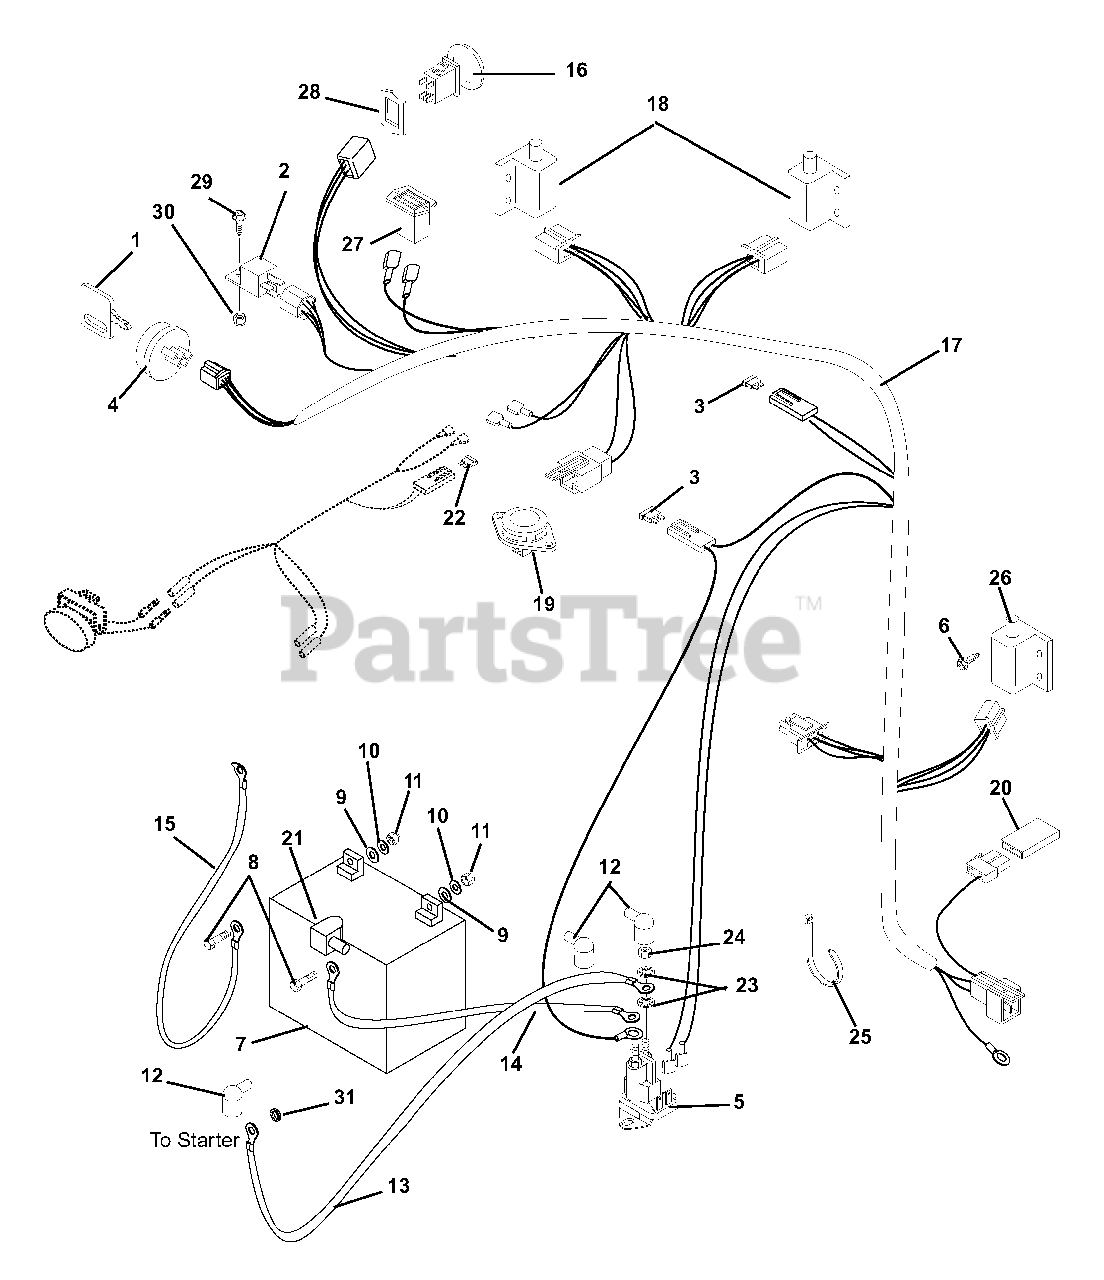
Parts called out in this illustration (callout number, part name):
1	KEY -W/CAP
2	RELAY
3	FUSE-25 AMP ATC TYPE
4	KEY SWITCH
5	SOLENOID
6	@SCR-TAP 10-24X.50 HWH TR YWZC
7	BATTERY, 300 CCA 10U1L
7	BATTERY W/ TUBE
8	@BLT-HEX .25-20X.75 GR5 YWZC
9	@WSHR-FL-STL.281X.62X.065 YWZC
10	@WSHR-LK .25X.062 REG YWZC
11	@NUT-HEX .25-20 YWZC
12	BOOT, EYELET TERMINAL
13	START CABLE 22"
14	STARTER CABLE 13"
15	GROUND CABLE .31X22.00X.31
16	SWITCH, CLUTCH
17	HARNESS, ZOOM/ZT
18	SWITCH- DOUBLE POLE N.O./N.O.
19	SWITCH- SNAP MTG N.O.
20	DIODE, CONNECTOR SHELL
21	INSULATOR
22	FUSE 20AMP
23	WSHR-LOCK INT .31 YWZC
24	NUT-JAM .31-24 YWZC
25	CABLE TIE LG 5-1/2
26	SWITCH,INTERLOCK
27	HOURMETER-QUARTZ 80VDCMAX
28	SHIM,PTO SW (DELTA #972301)
29	@SCR-MCH 10-24X.50 HWH YWZC
30	@NUT-LK-NYL 10-24 W/INSRT YWZC
31	GROMMET 1.0ID X 1.38 OD
